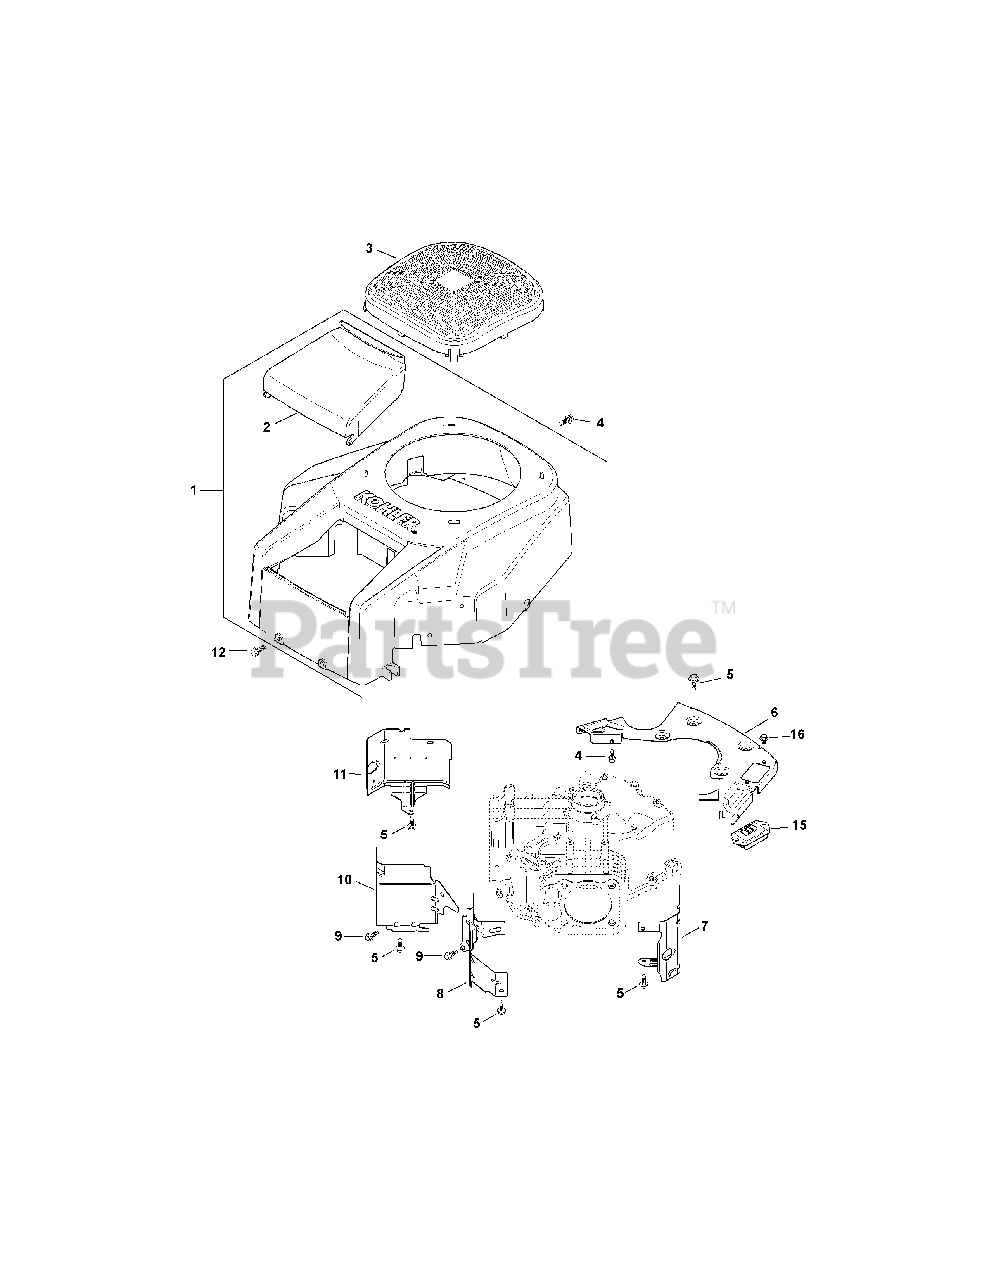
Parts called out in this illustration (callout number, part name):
1	Housing Blower Kit (Inc. 2 & KH-41-037-10-S)
2	Air Cleaner Cover
4	Flg. Thd. Frm. Screw, M5 X 0.8 X 16
5	Flg. Thd. Frm. Screw, M6 X 1.0 X 16
6	Backing Plate Kit
7	Cyl. Barrel Baffle - #2 Side
8	Valley Baffle - #2 Side
9	Flg. Thd. Frm. Screw, M5 X .8 X 10
10	Valley Baffle - #1 Side
11	Cyl. Barrel Baffle - #1 Side
12	Tap Screw, M6 X 1.7 X 18
15	Regulator/Rectifier
16	Flg. Thd. Frm. Screw, M6 X 1.0 X 10
